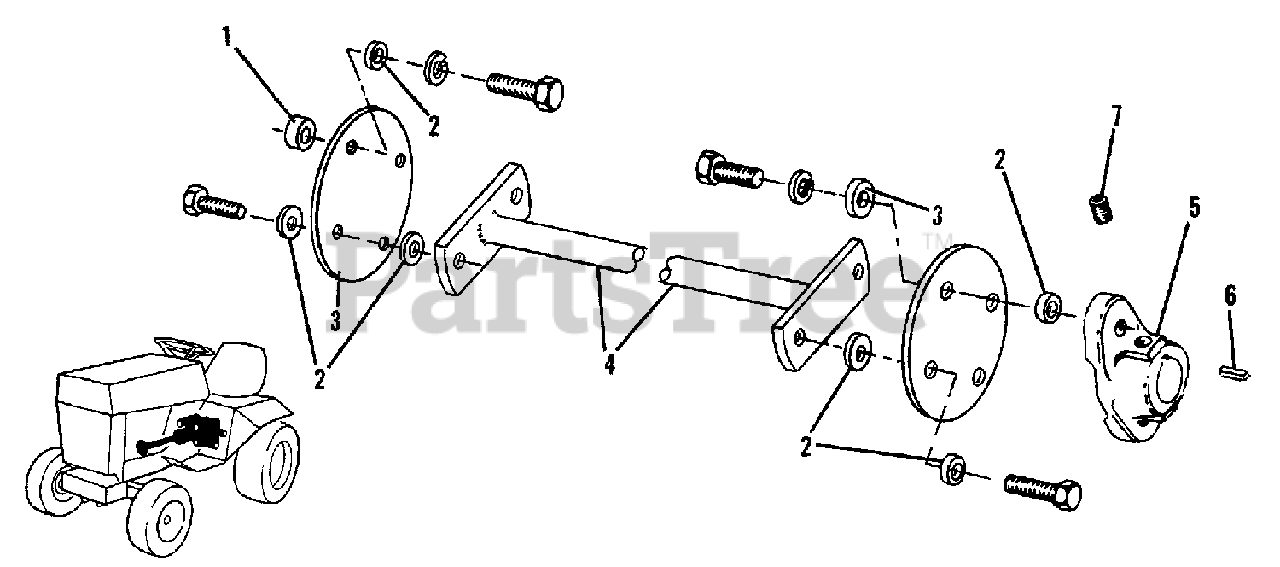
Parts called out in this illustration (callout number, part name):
2	WASHER, Special
3	PLATE, Drive Shaft Coupling
3	CAPSCREW, 3/8NC x 1-1/2
3	LOCKWASHER, 3/8
3	NUT, 3/8NC
4	SHAFT ASSEMBLY, Drive
5	FLANGE, (Prior to S/N's 15101001, 15201001, 15301001, 15401010, 15501031, 15601001, 15701001 & 15801077)
5	FLANGE, (Effective w/S/N's 15101001, 15201001, 15301001, 15401010, 15501031, 15601001, 15701001 & 15801077)
6	KEY, Special Parallel
7	SETSCREW, Socket Head, 3/8NF x 5/16
